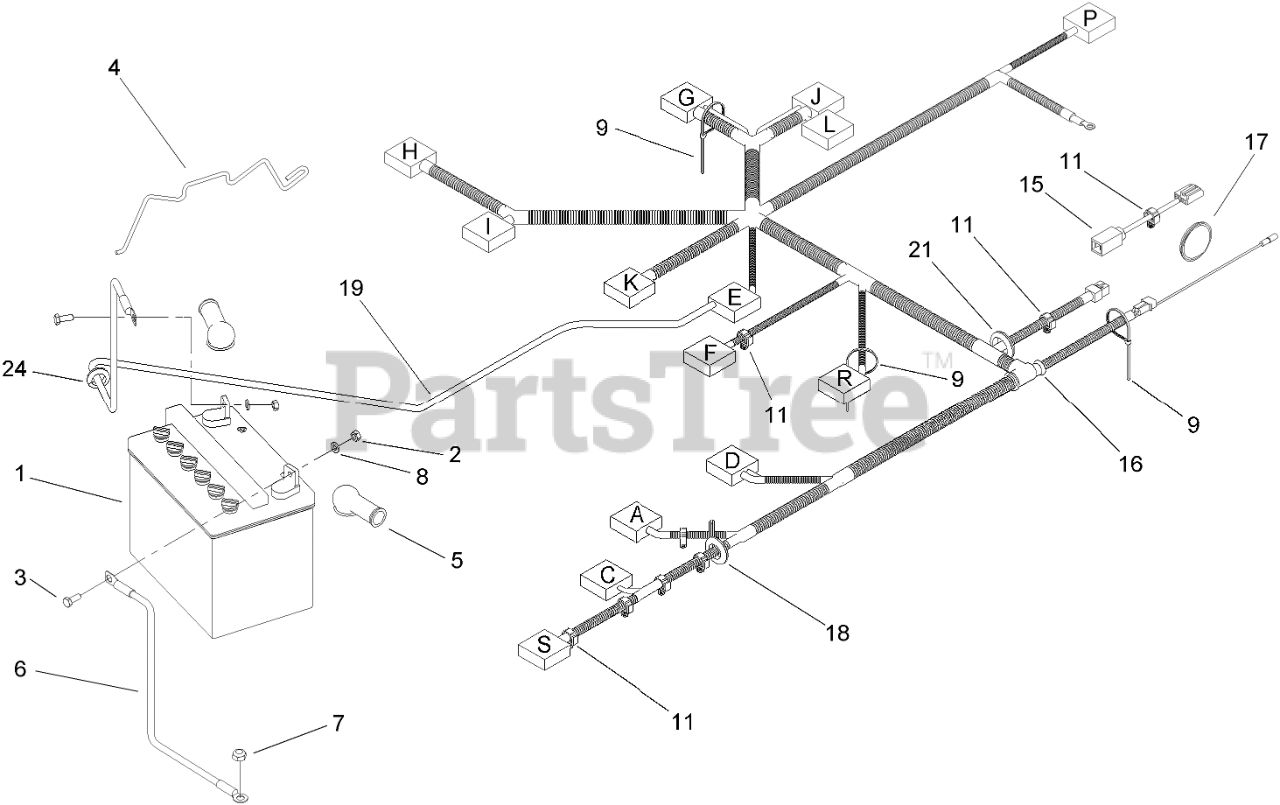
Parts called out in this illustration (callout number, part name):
1	BATTERY-12V
2	NUT-HEX
3	SCREW-HH
4	CLAMP-BATTERY
5	BOOT-RUBBER
6	CABLE-BATTERY, Negative
7	NUT-LOCK, NI
8	WASHER-FLAT
9	TIE-CABLE
11	CLIP-SNAP
15	HARNESS-CLUTCH
16	HARNESS-WIRING
18	BUSHING
19	CABLE-BATTERY POSITIVE
21	BUSHING
24	GROMMET
